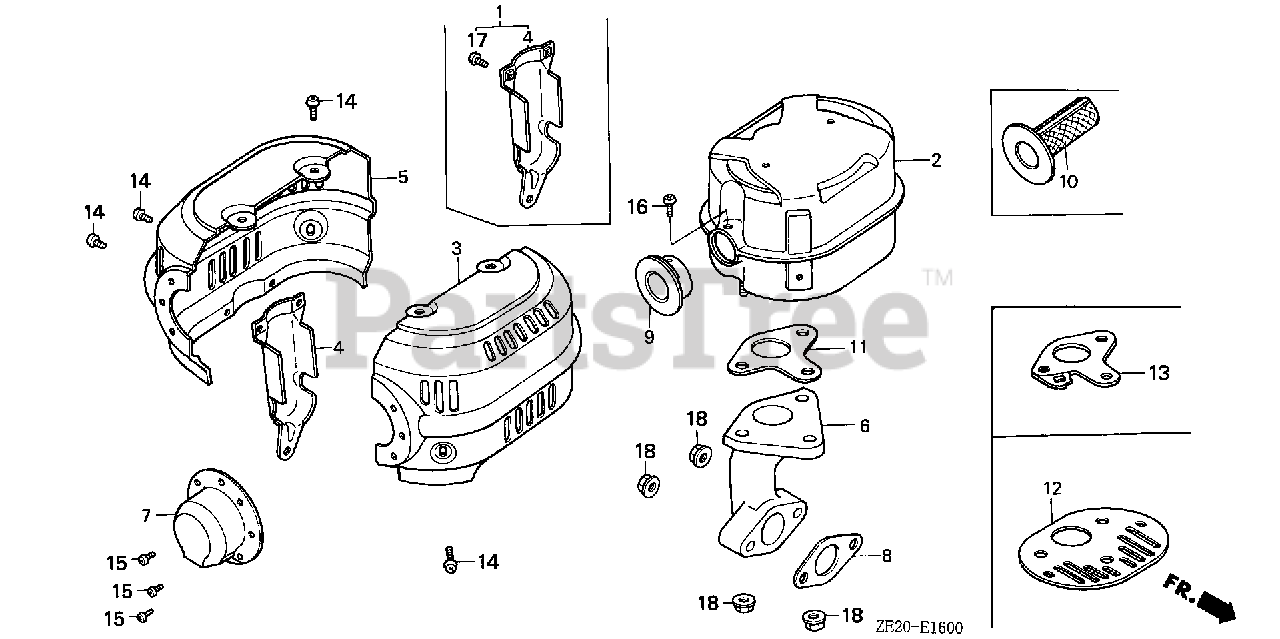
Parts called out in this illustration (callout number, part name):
1	PROTECTOR, EX. PIPE (NOT AVAILABLE)
3	PROTECTOR, R. MUFFLER (ALUMINIZED)
4	PROTECTOR, EX. PIPE
5	PROTECTOR, L. MUFFLER (ALUMINIZED)
7	CAP, MUFFLER
8	GASKET, EX. PIPE
11	GASKET, MUFFLER
11	GASKET, MUFFLER (NIPPON LEAKLESS)
14	SCREW, TAPPING (5X8)
15	SCREW, TAPPING (4X6)
17	SCREW, PAN (5X8)
18	NUT, FLANGE (8MM)
